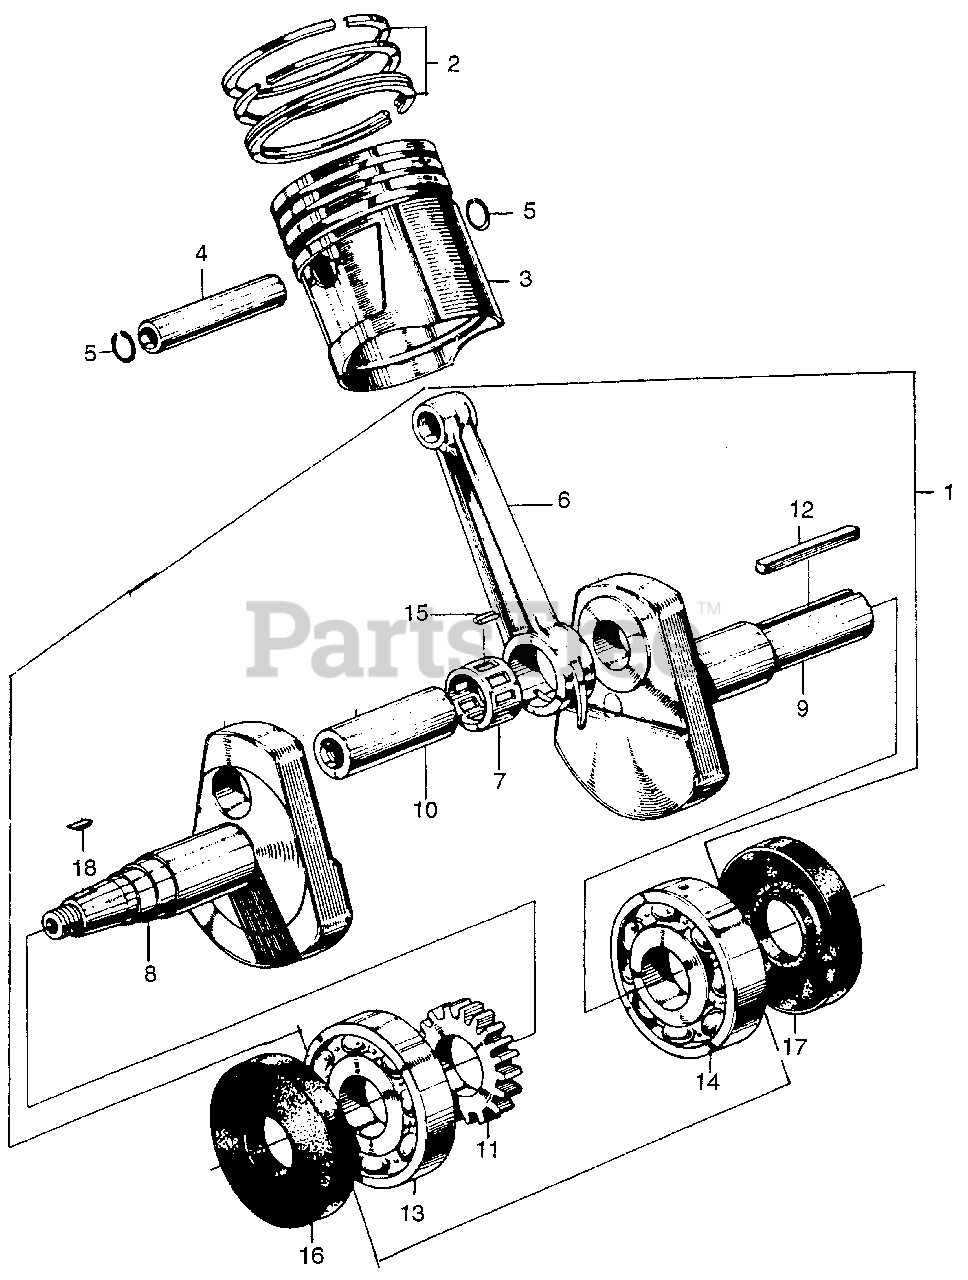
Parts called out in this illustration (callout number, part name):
1	CRANKSHAFT
2	RING SET, PISTON (STD)
2	RING SET, PISTON (OS 0.25)
2	RING SET, PISTON (OS 0.50)
3	PISTON (STD) (NOT AVAILABLE)
3	PISTON (OS 0.25)
3	PISTON (OS 0.50)
3	PISTON (0.75)
4	PIN, PISTON
5	CLIP, PISTON PIN (19MM)
6	ROD, CONNECTING (NOT AVAILABLE)
7	RETAINER, ROLLER
8	CRANKSHAFT, R. (NOT AVAILABLE)
9	CRANKSHAFT, L.
10	PIN, CRANK (N/A: SEE ASSEMBLY)
11	GEAR, TIMING
12	KEY (7X7X33)
13	BEARING, RADIAL BALL (6306S)
14	BEARING, BALL (6306)
14	BEARING, SPECIAL BALL (6306S6HS) (NOT AVAILABLE)
15	ROLLER, ROD (3X16)
16	OIL SEAL (30759) (NOT AVAILABLE)
17	OIL SEAL (PJ30779)
18	KEY, SPECIAL WOODRUFF (25X18)
